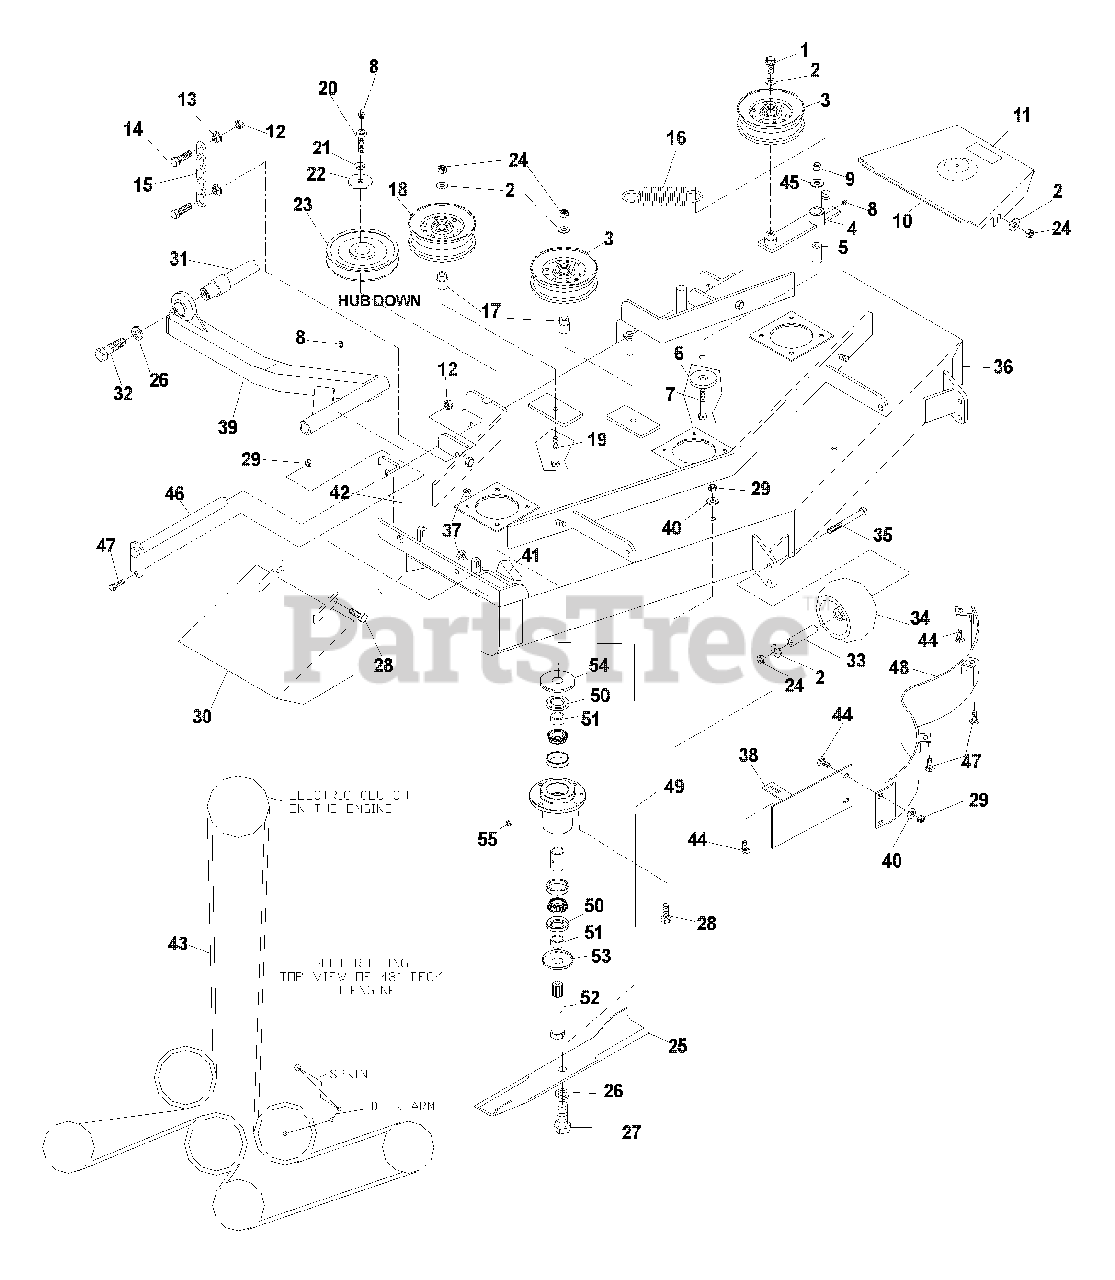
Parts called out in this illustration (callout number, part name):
1	HCS 3/8C X 1 SERRATED HD
2	WASHER 3/8 FLAT
3	IDLER PULLEY
5	PIVOT BUSHING
6	SUPPORT WASHER
7	HCS 1/2C X 3 1/4
8	ZERK
9	NUT 1/2C NYLOC
10	BELT SHIELD, LEFT
11	DECAL, NO STEP
12	NUT 7/16C CENTERLOCK
13	7/16C WHIZ NUT
14	HCS 7/16C X 1 1/2
15	LIFT CHAIN
17	IDLER BUSHING
18	IDLER PULLEY(TALL)
19	HCS 3/8C X 2 3/4
20	HCS 7/16F X 1 1/2,SPEC.
21	LOCKWASHER 7/16
22	HEAVY WASHER
23	PULLEY
24	NUT 3/8C, NYLOC
25	16 1/4" BLADE
26	LOCKWASHER 5/8
27	HCS 5/8F X 1 1/4
28	HCS 5/16C X 1 1/4
29	NUT 5/16C CENTERLOCK
30	DEFLECTOR CHUTE
31	STRUT MOUNT
32	HCS 5/8C X 2 GR.5
34	ANTI-SCALP ROLLER
35	HCS 3/8C X 3 1/2
36	DECK W/DECALS
37	NUT 5/16C, NYLOC
38	CENTER BAFFLE
39	STRUT - RT
40	5/16 FLAT WASHER
41	DECAL, CPSC
42	DECAL, DANGER
43	48" DECK BELT
44	CARRIAGE BOLT
45	WASHER 1/2 FLAT
47	HCS 5/16C X 3/4
48	MAIN BAFFLE
49	COMPLETE HOUSING
50	SHAFT SEAL
52	MINI SPINDLE
53	DUST CAP, BOTTOM
54	DUST CAP, TOP
55	GREASE POPET
